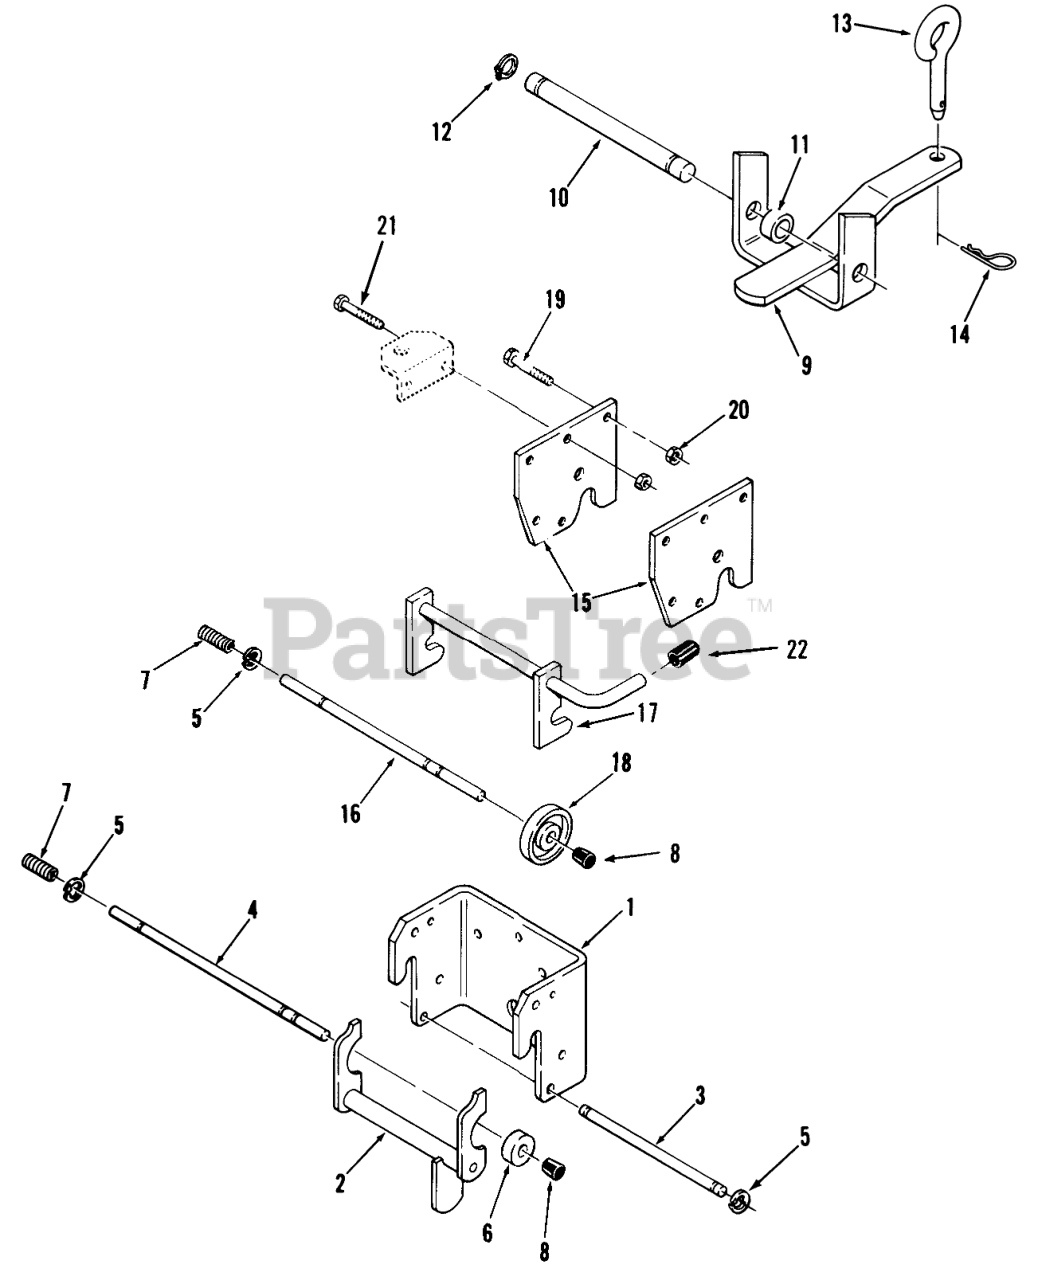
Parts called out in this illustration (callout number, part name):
1	Front Hitch
2	Assy-Latch
3	ROD-LATCH PIVOT
4	ROD-LOCK
5	RING-RETAINING
7	SPRING
8	CAP-ROD, PLUNGER
9	Hitch
10	PIN-STATIONARY HITCH
11	Spacer
12	E-RING
13	PIN-TOOL
14	Hairpin Cotter
15	Hitch Plate
17	MID HITCH ASM
19	BOLT
20	NUT
21	Bolt
22	GRIP
